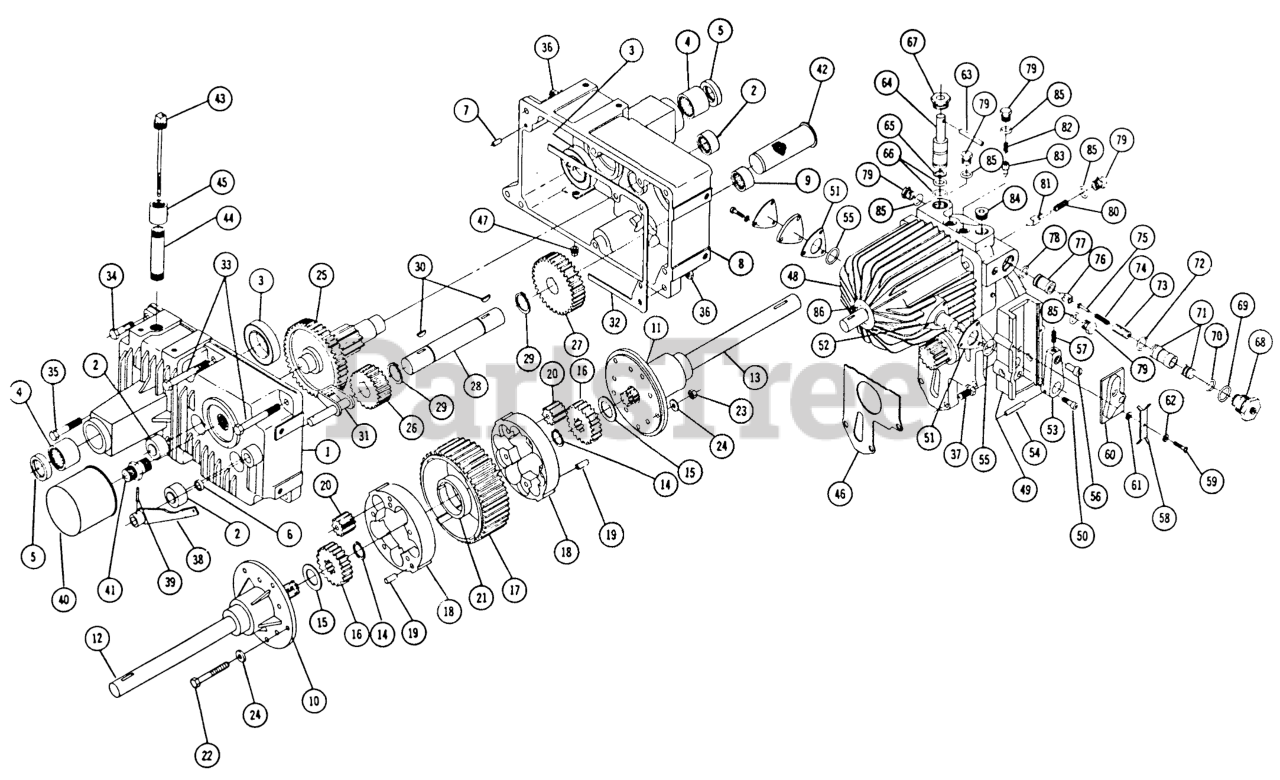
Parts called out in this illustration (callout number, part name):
1	Case R.H.
2	BEARING-NEEDLE
3	BALL BRG 1 1/2 I.D.
4	Bearing-Axle
5	SEAL-OIL
6	SEAL BRAKE SHAFT
7	PIN-DOWEL
8	Case LH
9	NEEDLE BEARING
10	End Cap-RH
11	End Cap-LH
12	Axle, R.H.
13	Axle, L.H.
14	SNAP RING
15	THRUST WASHER
16	SIDE GEAR
17	Gear-Ring
18	Body
19	SPIROL ROLL PIN
20	PINION
21	Spring
22	Bolt Hex 3 1/4
23	3/8-16 E.S.
24	Washer
25	Gear
26	GEAR
27	Gear-33 Teeth
28	SHAFT GEAR
29	Snap Ring
30	Key
31	Assy.-Park Brake
32	GASKET
33	Bolt Hex 3/8-16 x 5
34	Bolt, 3/8 16 x 2
35	Bolt Hex 3/8-16 x 1
37	Bolt, 3/8-16 x 1
38	Assy. Lever-Brake
39	Pin-Roll
40	Filter
41	FITTING
42	Strainer
43	Dipstick
44	Nipple 1/2 Pipe x 31/2
45	Coupling 1/2 Pipe
46	GASKET PUMP
47	PLUG 1/4 PIPE ALLEN
48	Hydrogear
49	SUPPORT CAM BLOCK
50	SHCS 1/4-20 X 1/2
51	Shim
52	O-Ring
53	Arm-Cam Follower
54	ROLL PIN 1/4 X 1-1/4
56	ECC CAM FOLLOWER
57	Set Screw-1/4-20 x 1/2
58	TENSION PLATE
59	Bolt-Rd. Heed #8-32 x 1/2
60	CAM
61	Washer
62	Lockwasher
63	SPIROL PIN
64	VALVE
65	RING BACK UP
66	O-Ring
67	PLUG
68	Ass-y Dampening Valve & Ring
69	O RING
70	O RING
71	Ass-y Piston & Sleeve (Matched)
72	O RING
73	SPRING
74	SPRING
75	SUNDSTRAND 3100047
76	Cone-Relief Valve
77	SLEEVE RELIEF VALVE
78	O RING
79	Plug
80	SPRING-SUNDSTRAND
81	Valve
82	Spring Charge Pump Valve
83	Cone
85	O RING
86	SEAL
